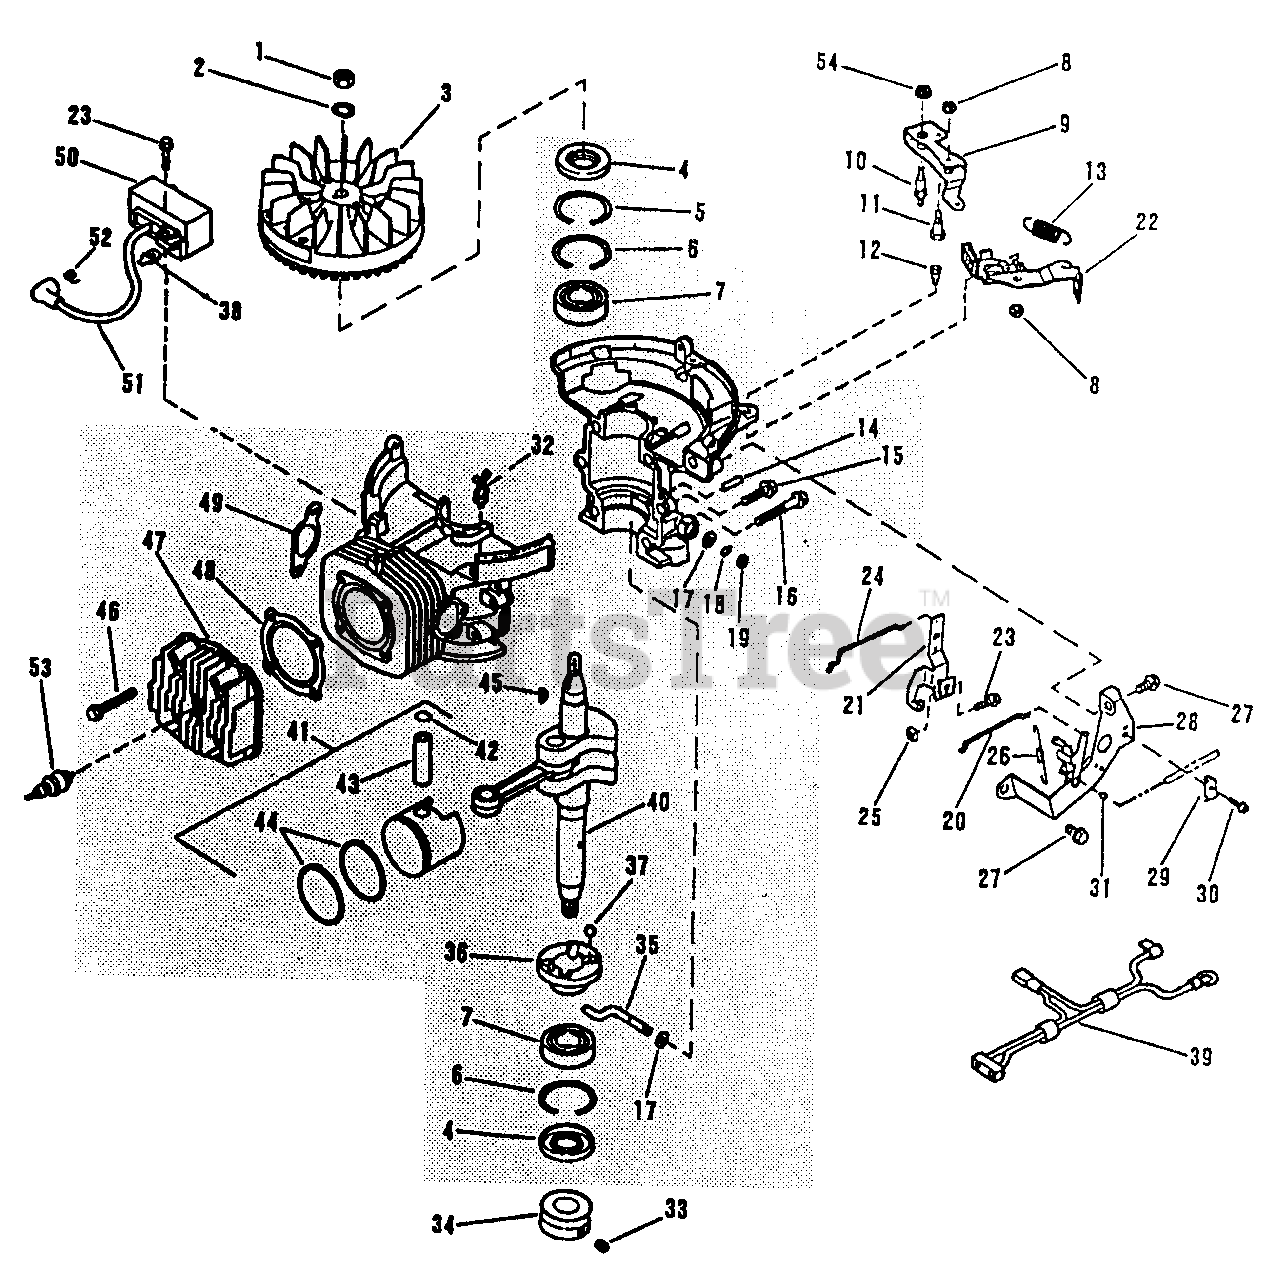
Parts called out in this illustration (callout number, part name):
1	Nut-Flywheel
2	Lockwasher-Flywheel
3	Flywheel
4	Oil Seal-Crankshaft
5	Retaining Ring
6	Retaining Ring
7	Bearing-Crankshaft
8	Locknut
9	Brake Actuator Lever
10	Shoulder Stud-Actuator Lever
11	Shoulder Bolt
12	Shoulder Bolt
13	Brake Spring
14	Taper Pin
15	Screw-Crankcase
16	Screw-Crankcase
17	Washer-Governor Shaft
18	Retainer Ring-Govrenor Shaft
19	Oil Seal-Governor Shaft
20	Choke Rod
21	Governor Control Lever
22	Brake and Switch Kit
24	Throttle Rod
25	Nut-Governor Lever
26	Governor Spring
27	Screw-Governor Bracket
28	Governor Bracket Assembly
29	Clamp-Throttle Cable to Bracket
30	Screw-Cable Bracket
31	Throttle Control Wire Retainer
32	Wire Tie
33	Set Screw-Pulley (ZMRA & B)
34	Engine Pulley (ZMRA & B)
35	Governor Shaft
36	Governor Ramp
37	Governor Ball
38	Terminal-C.D. Ignition Module
39	Wire Harness
40	Crankshaft and Connecting Rod
41	Piston and Ring Assy. (Standard)
42	Retaining Ring
43	Wrist Pin
44	Ring Set (Standard)
45	Key-flywheel
46	Screw-Cylinder Head to Block
47	Cylinder Head
48	Head Gasket
49	Exhaust Gasket
50	C.D. Ignition Module
51	High Tension Lead and Cover
52	Spring Terminal
53	Spark Plug
54	Hex Flang Nut
